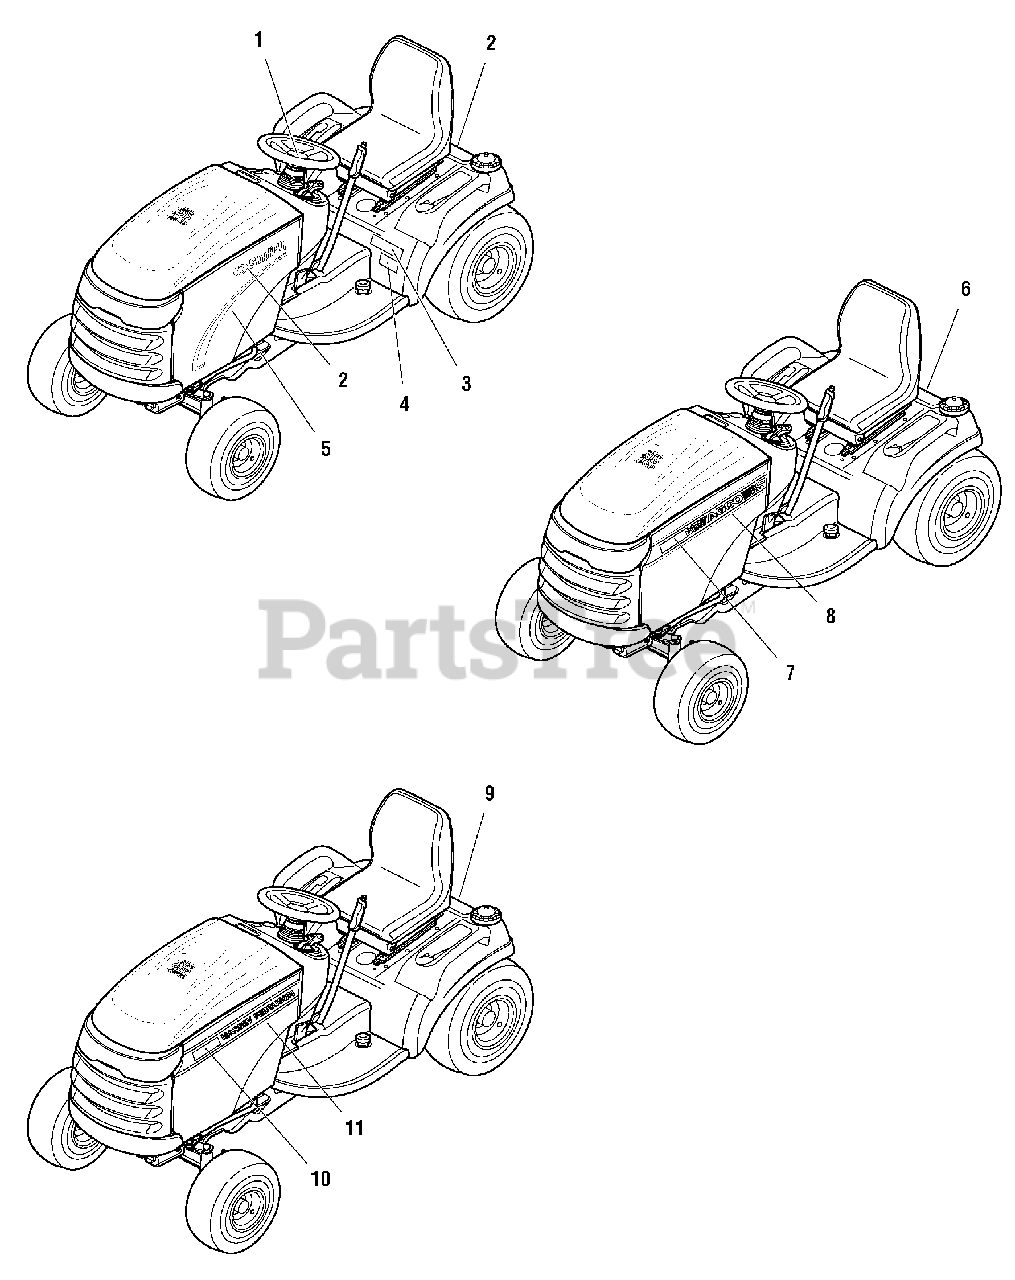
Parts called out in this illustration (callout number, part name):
1	DECAL, ICON Simplicity, Orange
2	DECAL, Simplicity, Silver & Blue w/Icon
3	DECAL, Conquest, Silver & Blue
4	DECAL, 16HP, Silver On Clear
4	DECAL, 18HP, Silver On Clear
4	DECAL, 20HP, Silver On Clear
4	DECAL, 21HP, Silver On Clear
4	DECAL, 23HP, Silver On Clear
4	DECAL, 24HP, Silver On Clear
5	DECAL, Hood Stripe, RH, Simplicity, Blue & Silver
5	DECAL, Hood Stripe, LH, Simplicity, Blue & Silver
6	DECAL, AGCO, Logo Black, Chrome, Orange
7	DECAL, 1716, Gray, AGCO
7	DECAL, 1718, Gray, AGCO
7	DECAL, 1720, Gray, AGCO
7	DECAL, 1721, AGCO
8	DECAL, Hood Stripe, LH, AGCO
8	DECAL, Hood Stripe, RH, AGCO
9	DECAL, Massey Ferguson Logo, 3 Triangles
10	DECAL, 2700, Massey Ferguson
10	DECAL, 2700, 24-52, Massey Ferguson
10	DECAL, 2700, 26-52 PS, Massey Ferguson
10	DECAL, 2718, Black, Massey Ferguson
10	DECAL, 2720, Black, Massey Ferguson
10	DECAL, 2721, Massey Ferguson
10	DECAL, 2723, Massey Ferguson
10	DECAL, 2724, Massey Ferguson
10	DECAL, 2716, Black, Massey Ferguson
11	DECAL, Hood Stripe, LH, Massey Ferguson
11	DECAL, Hood Stripe, RH, Massey Ferguson
11	DECAL, Hood Stripe, LH, Massey Ferguson Baron
11	DECAL, Hood Stripe, RH, Massey Ferguson Baron
12	DECAL, Power Steering
